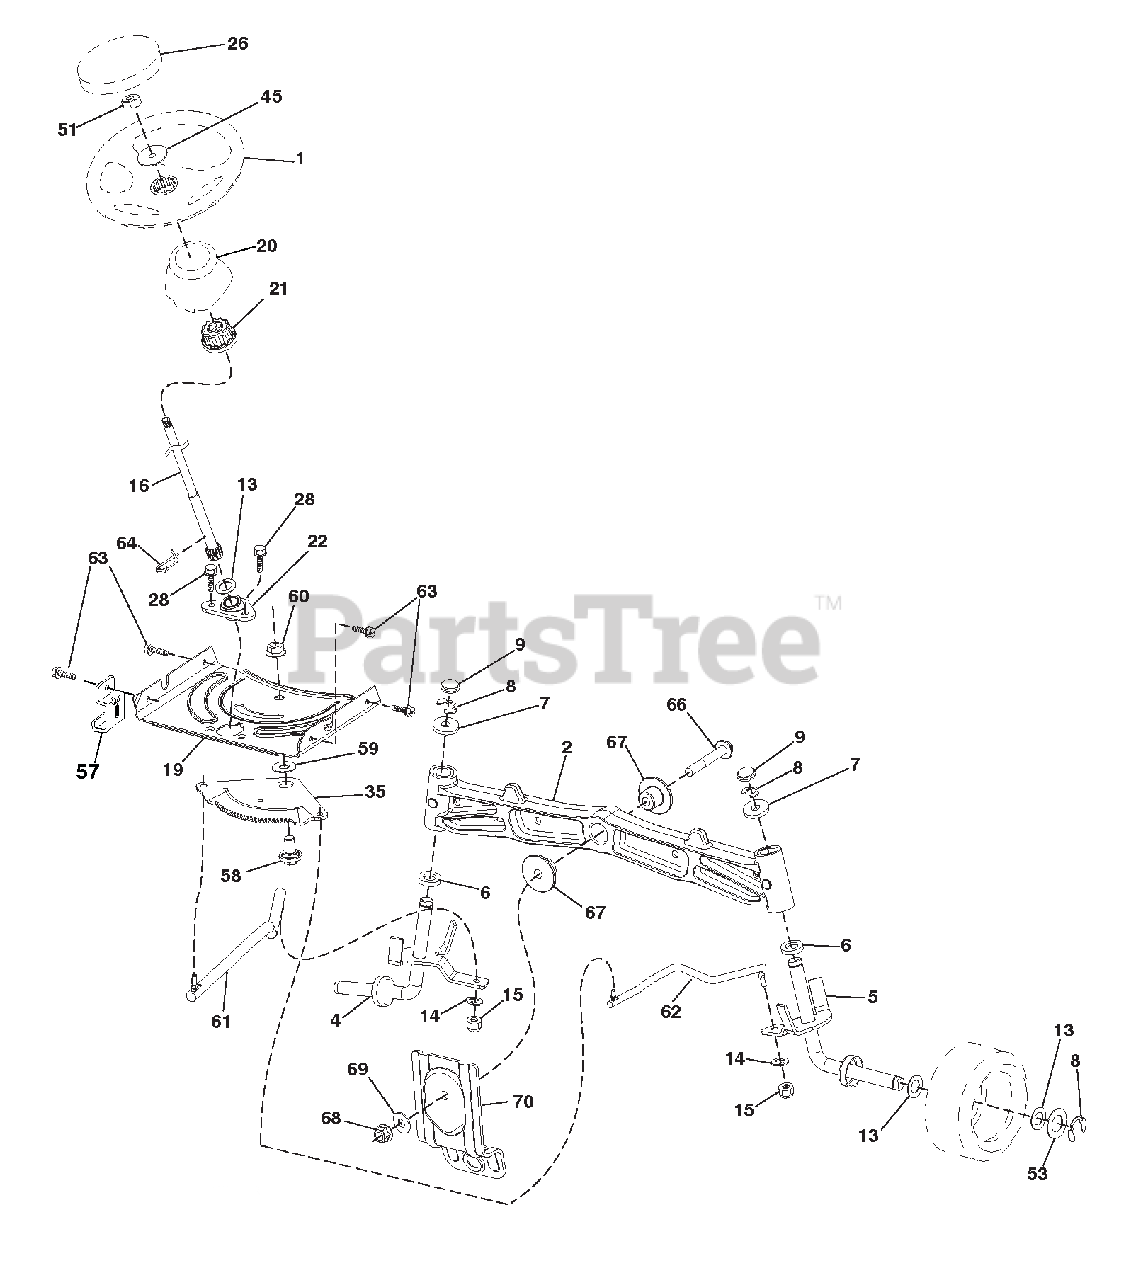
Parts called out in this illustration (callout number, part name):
1	WHEEL STEERING
2	AXLE.CAST IRON
4	SPINDLE.WELDED.LH.15"TEX
5	SPINDLE.WELDED.RH.15"TEX
6	WAHSER THRUST .75 X 1.230
7	WASHER.25/32 X 1-5/8 X 16GA.
8	RING.KLIP.#T5304-75
9	CAP.SPINDLE.FR.TOP.BLK.
13	WASHER.25/32 X 1 1/4 X 16 GA.
14	Washer, Lock 3/8
15	NUT.CROWNLOCK.3/8-24
16	SHAFT.STEER.3/4 TEX.NON-PLATED
19	PLATE.STEER.DDL.NLT/NGT
20	BOOT STEERING LT TEX P/L .428
21	ADAPTER.WHEEL.STRG..760
22	STEERING SUPT. LOWER
26	CAP WHEEL STEERING HRS/SRS BLK
28	SCREW.HEXWSH THDR3/8-16X3/4.BL
35	GEAR SECTOR.PLATE.DDL.NLT/NGT
45	WASHER.11/32ID X2 3/8OD X 12GA
51	NUT.HEX.JAM.TOPLOCK.1/2-20 UNF
53	WASHER.HARDEN..793 X 1.637X060
57	BRACKET.UPSTOP.GT/LT.TEX
58	BOLT.SHOULDER.SECTOR.PIVOT.CFM
59	WASHER.THRUST.SECTOR.STEER.NLT
60	NUT.FLANGE LOCK.5/8-11
61	DRAGLINK.LH.BALLSTUD.DDL.
62	DRAGLINK.RH.BALLSTUD.DDL
63	SCREW.5/16-18X3/4.SMGML.TAP/BL
64	RETAINER.CLIP.SPRING.STEERING
66	BOLT.HEX.FGHD.7/16-14 X 3.SERR
67	BUSHING.PM.FRONT AXLE
68	NUT.LOCK.FLANGE.7/16-14.GR5
69	WASHER.1.5 X .505 X .118
70	BRACKET.DECK.SUSPENSION.FRONT
